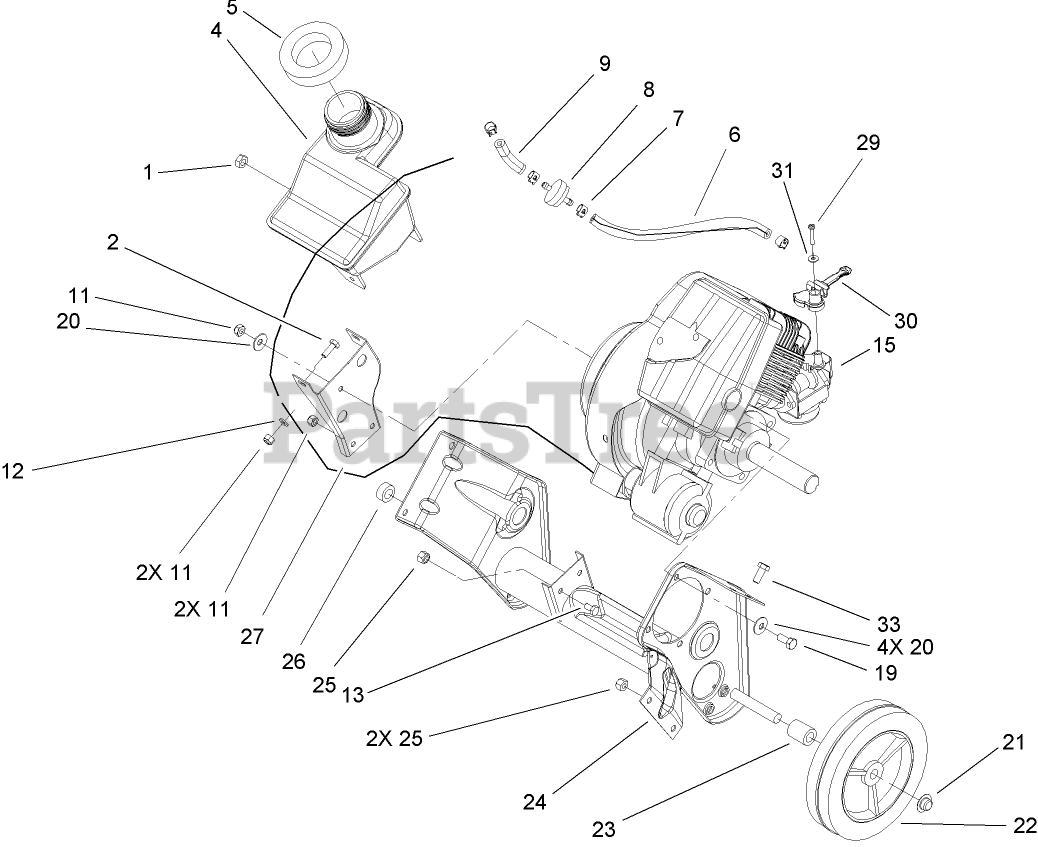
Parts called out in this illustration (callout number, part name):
1	NUT-LOCK, CONE
2	SCREW-HH
4	TANK-GAS
5	SEAL-FOAM
6	LINE-FUEL
7	CLAMP-HOSE
8	FILTER-FUEL
11	NUT-LOCK, NI
12	WASHER-FLAT
13	SCREW-HH
19	SCREW-HH
20	WASHER-BELLEVILLE
21	NUT-PUSH
22	WHEEL
23	SPACER-WHEEL
25	NUT-LOCK, NI
26	SPACER-WHEEL
27	BRACKET-SUPPORT, RECOIL
29	SCREW-PPH, PLASTITE
30	LEVER-CHOKE
31	WASHER-FLAT
33	SCREW-HH
